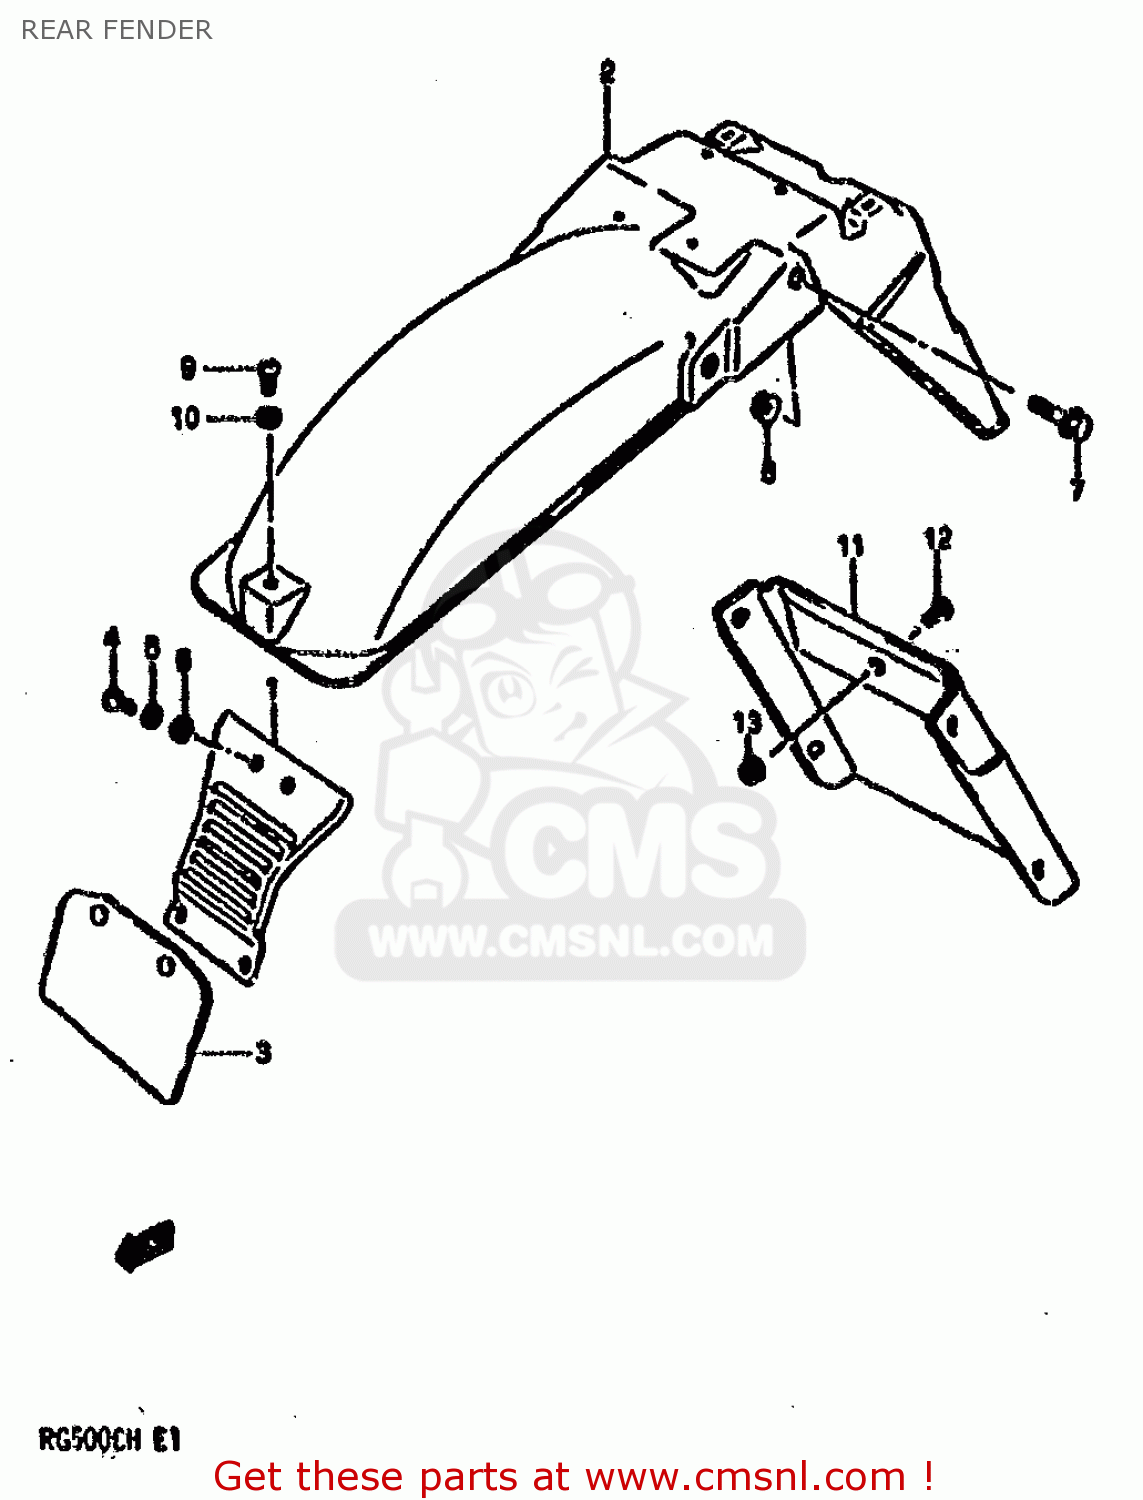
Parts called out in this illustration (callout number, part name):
1	FENDER,REAR FRONT
2	FENDER,REAR
3	GUARD,REAR FENDER MUD
4	SCREW
5	WASHER,LOCK
6	WASHER
7	BOLT 8X40
8	NUT
9	SCREW
10	WASHER
11	EXTENSION,REAR FENDER
12	SCREW, FRONT & REAR
13	NUT
